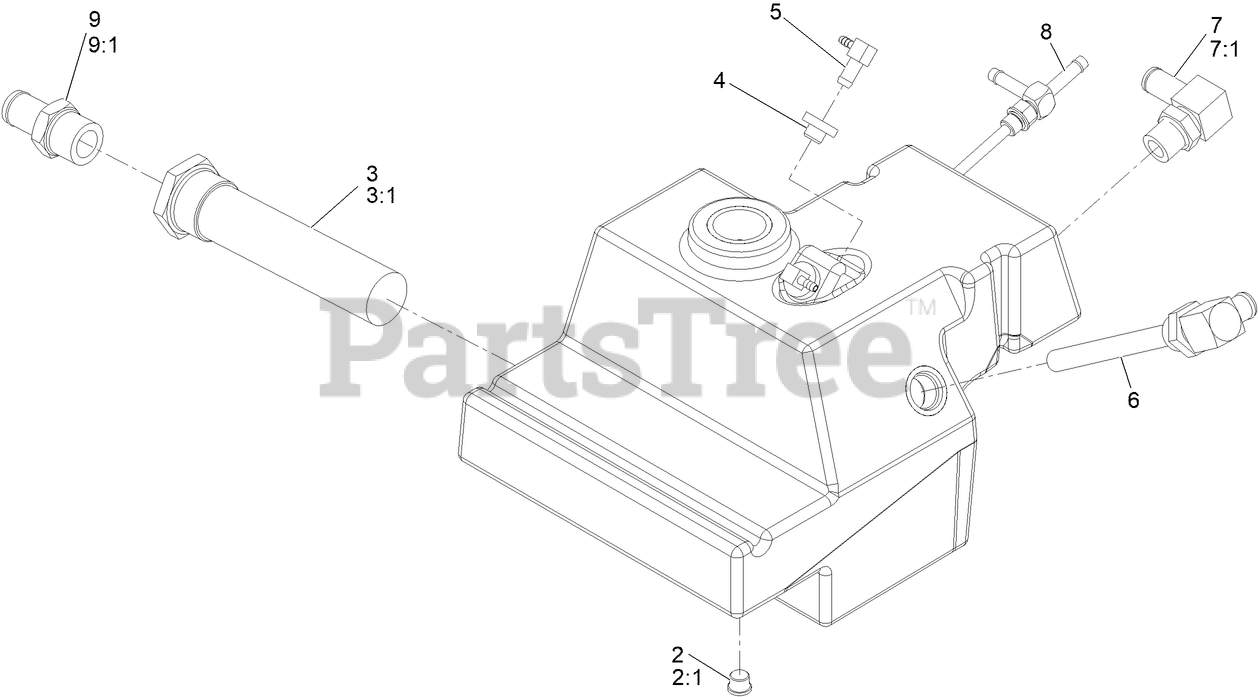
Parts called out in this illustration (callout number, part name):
2	PLUG-HEX, HOLLOW
2:1	O-RING
3	Strainer-In Tank
4	BUSHING
5	FITTING-ELBOW, 90 DEG
6	Fitting-Standpipe
7	FITTING-ELBOW, 90
7:1	O-RING
8	FITTING-TEE, DROP TUBE
9	Fitting-STR
